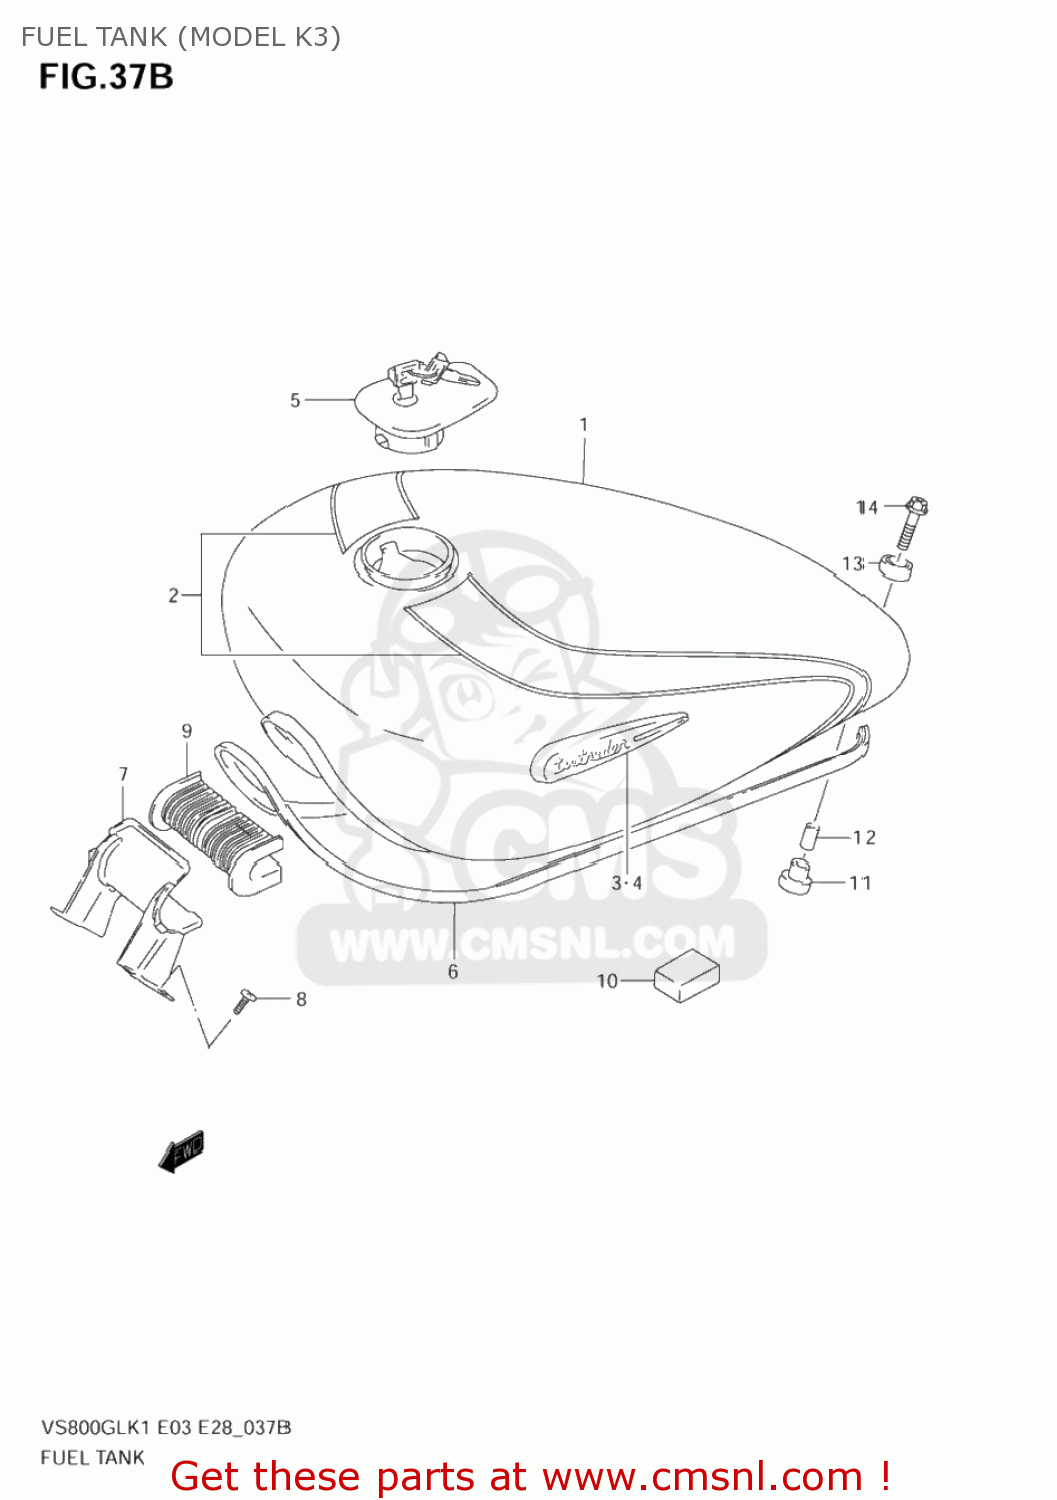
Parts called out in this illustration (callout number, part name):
1	TANK ASSY,FUEL(BLACK)
2	TAPE SET,FUEL TANK
3	EMBLEM,FUEL TANK,R
4	EMBLEM,FUEL TANK,L
5	CAP SET,FUEL TANK
6	MOLDING
7	BRACKET,FUEL TANK FR
8	SCREW
9	CUSHION,FUEL TANK FR
10	CUSHION
11	CUSHION
12	SPACER(6.5X9X21.5)
13	CUSHION
14	SCREW(6X35)
